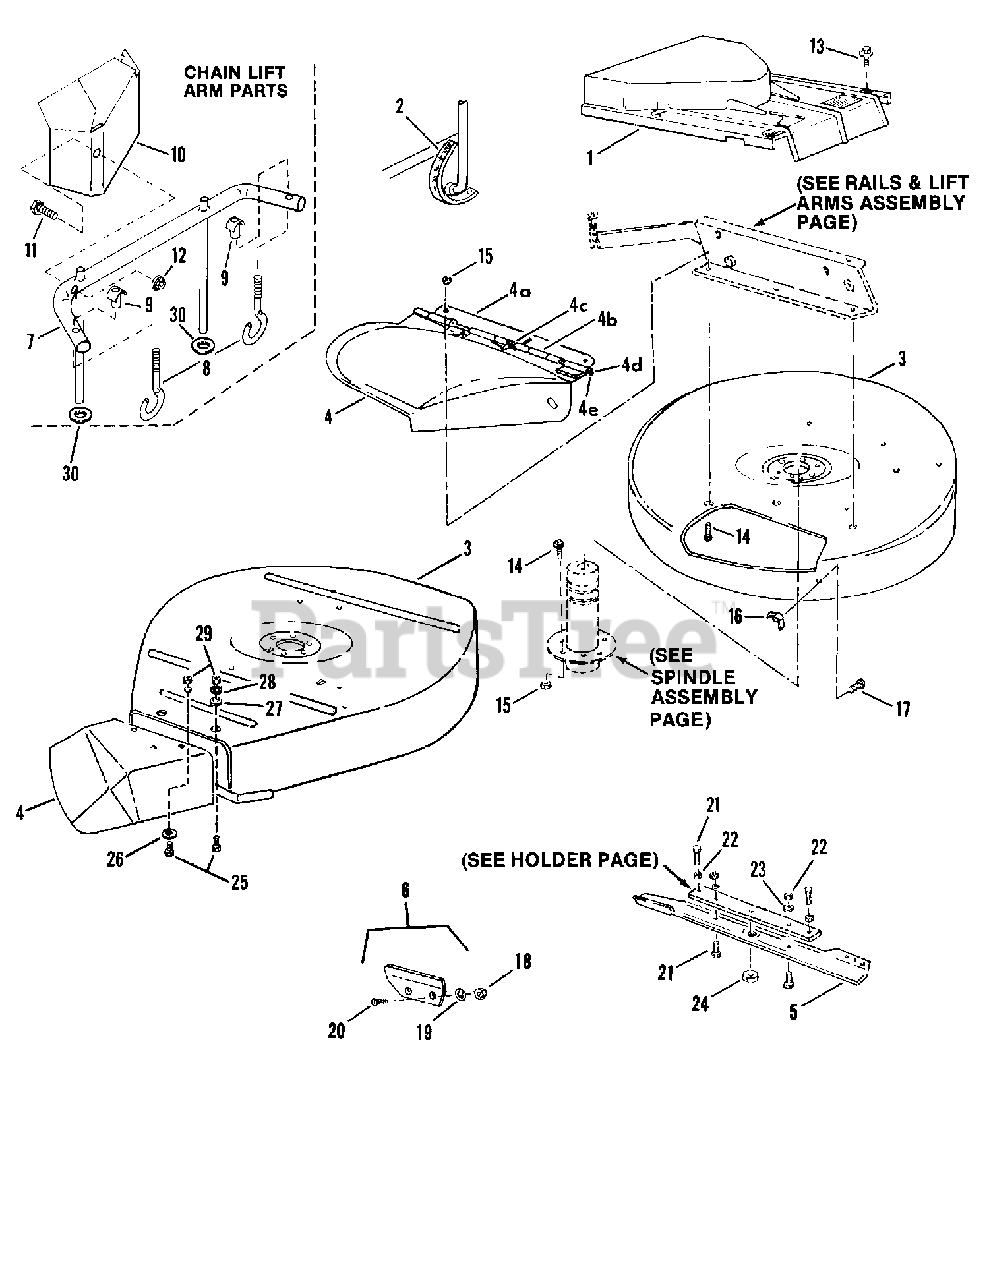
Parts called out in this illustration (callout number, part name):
1	COVER, Spindle
2	INDICATOR PLATE
3	28" DECK (Includes decals)
3	30" DECK (Includes decals & deflector)
3	33" DECK (Includes decals)
4	28" & 33" DEFLECTOR ASS'Y
4	30" DEFLECTOR
4A	HINGE
4B	28" & 33" DEFLECTOR, Discharge
4C	SPRING, Hinge
4D	PIN, Hinge
4E	WASHERS, Flat
5	28" BLADE
5	30" BLADE
5	33" BLADE
6	AIR LIFT KIT, Standard (2 hole)
7	ARM, Chain Lift
8	HOOK, Chain
9	NUT, Chain Adjusting
10	SHIELD, Exhaust Heat
11	CAPSCREW, 1/4-28x1-1/2 Hex Head
12	LOCKNUT, 1/4-28 Hex Flange
13	SCREW, 1/4-20x5/8 Hex Washer Self-tapping
14	SCREW, 3/8-24x3/4 Hex Head Cap
15	LOCKNUT 3/8-24 Hex
16	WING-NUT, 5/16-18
17	BOLT, 5/16-18x3/4 Carriage
18	NUT, 5/16-24 Hex
19	LOCKWASHER, 5/16 Int. Tooth
20	SCREW, 5/16-24 Hex
21	SCREW, 1/2-20x1 Hex Head Cap
22	JAM-NUT, 1/2-20
23	LOCKWASHER, 1/2 Int. Tooth
24	LOCKNUT, 5/8-18 Hex
25	SCREW, 1/4-28x3/4 Hex Head Cap
26	WASHER, Fender
27	LOCKWASHER, 1/4 Internal Tooth
28	WASHER, 1/4 SAE
29	NUT, 1/4-28 Hex
30	WASHER, 5/8 SAE
